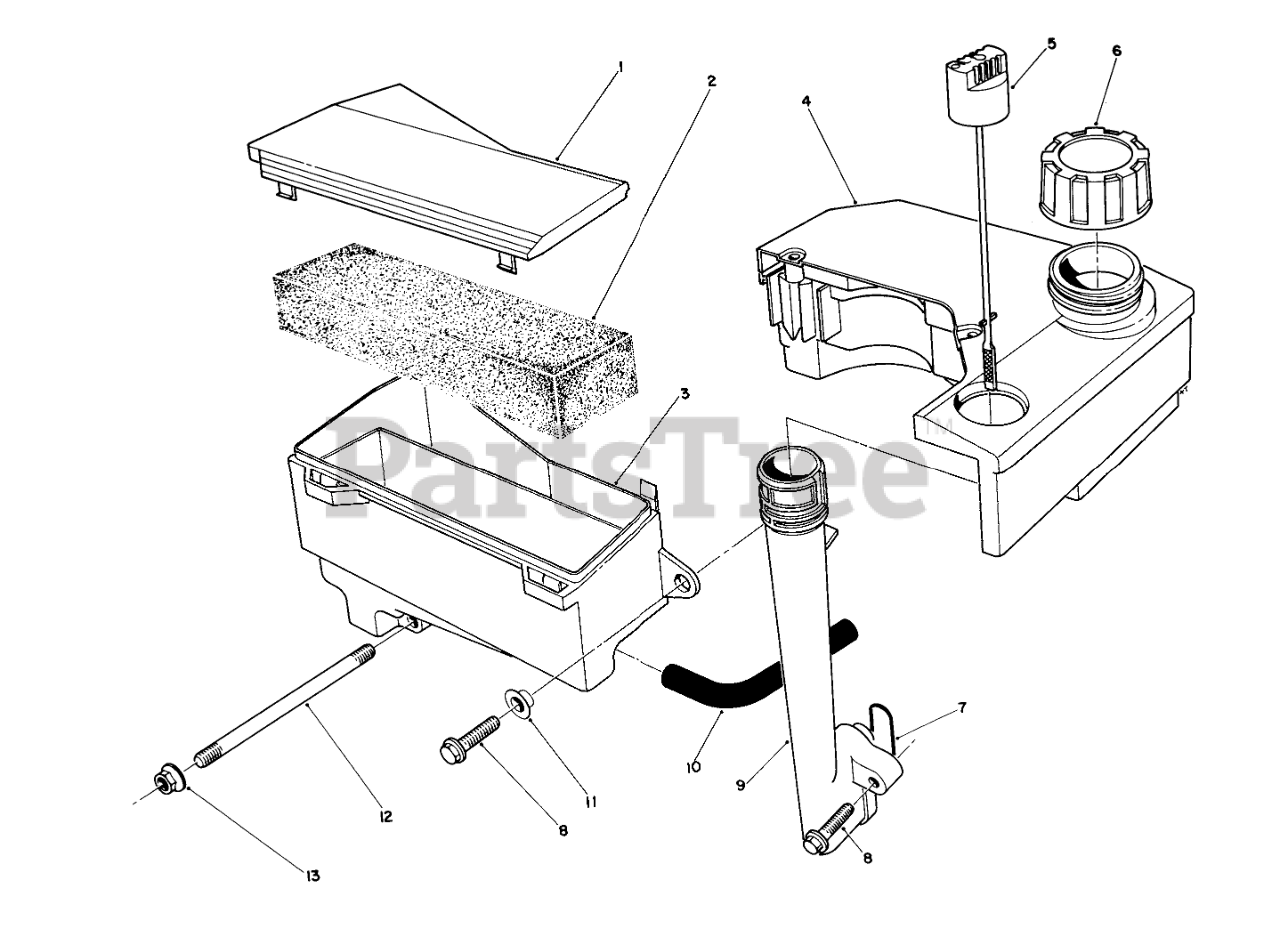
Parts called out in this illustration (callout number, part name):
1	AIR CLEANER CAP
3	Body-Air Cleaner
4	TANK ASM
5	Dipstick
6	GAS CAP ASM
7	O-RING
11	SPACER
12	Stud-Carburetor
